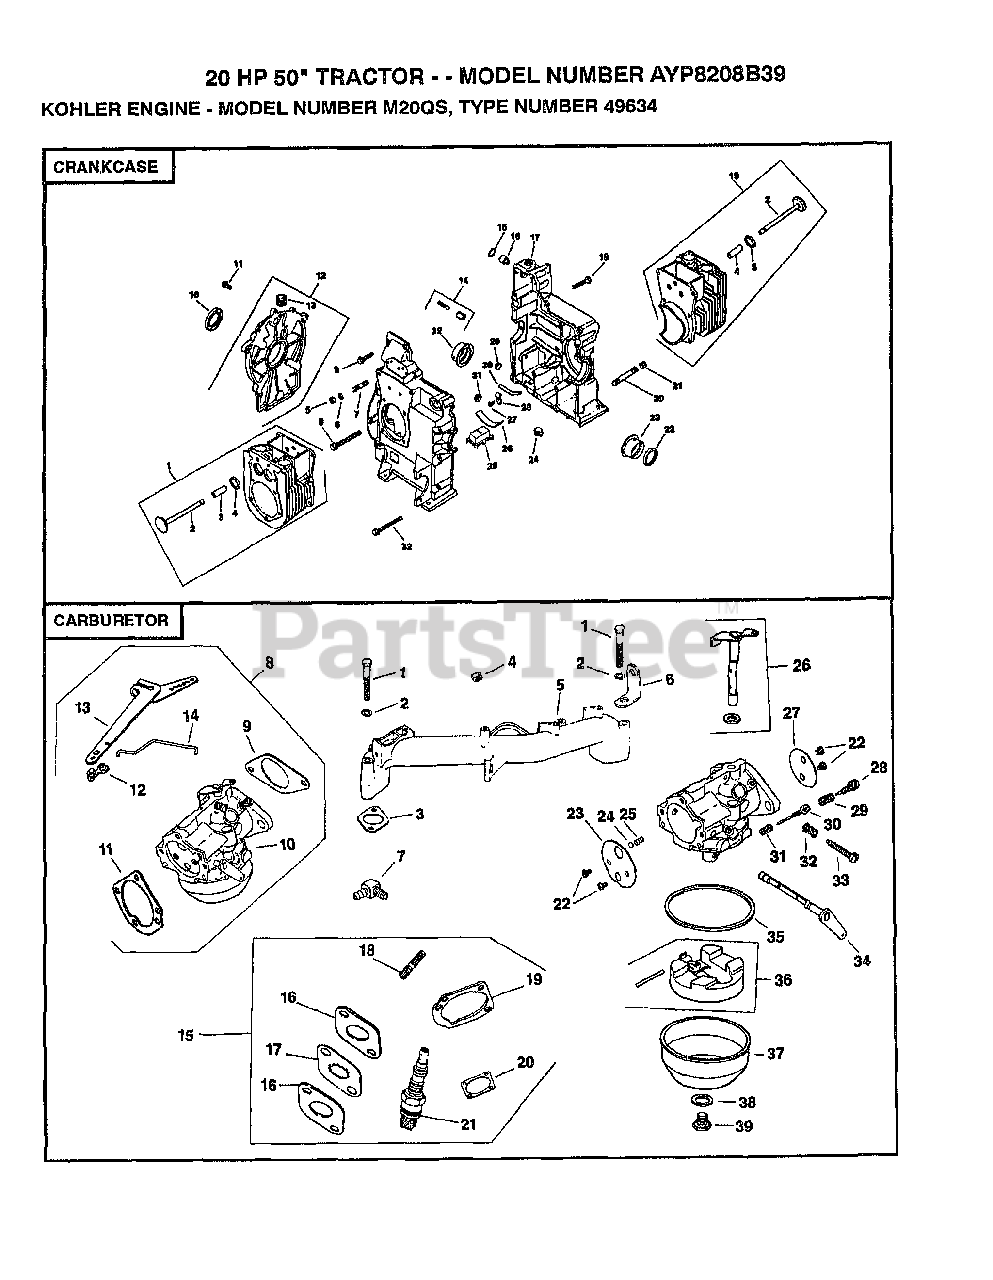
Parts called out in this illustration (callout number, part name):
1	SCREW
2	WASHER
4	NUT
5	NUT
5	MANIFOLD, INTAKE
6	STRAP, LIFTING
8	KIT, CARBURETOR WITH GASKET
9	GASKET
10	SEAL
11	SCREW
11	GASKET, AIR CLEANER
12	KIT, CLOSURE PLATE
13	PLUG
13	ARM, GOVERNOR
14	KIT, GOVERNOR LINKAGE
15	RING, RETAINING
15	KIT, CARBURETOR BAFFLE
16	GASKET
19	GASKET, AIR CLEANER
20	GASKET
24	PLUG
25	HOUSING, OIL PICKUP
26	CLAMP, SPRING
26	SHAFT, THROTTLE WITH LEVER AND SEAL
27	SCREW
29	PLUG, CUP
30	TUBE, DIPSTICK
39	SCREW, BOWL RETAINER
